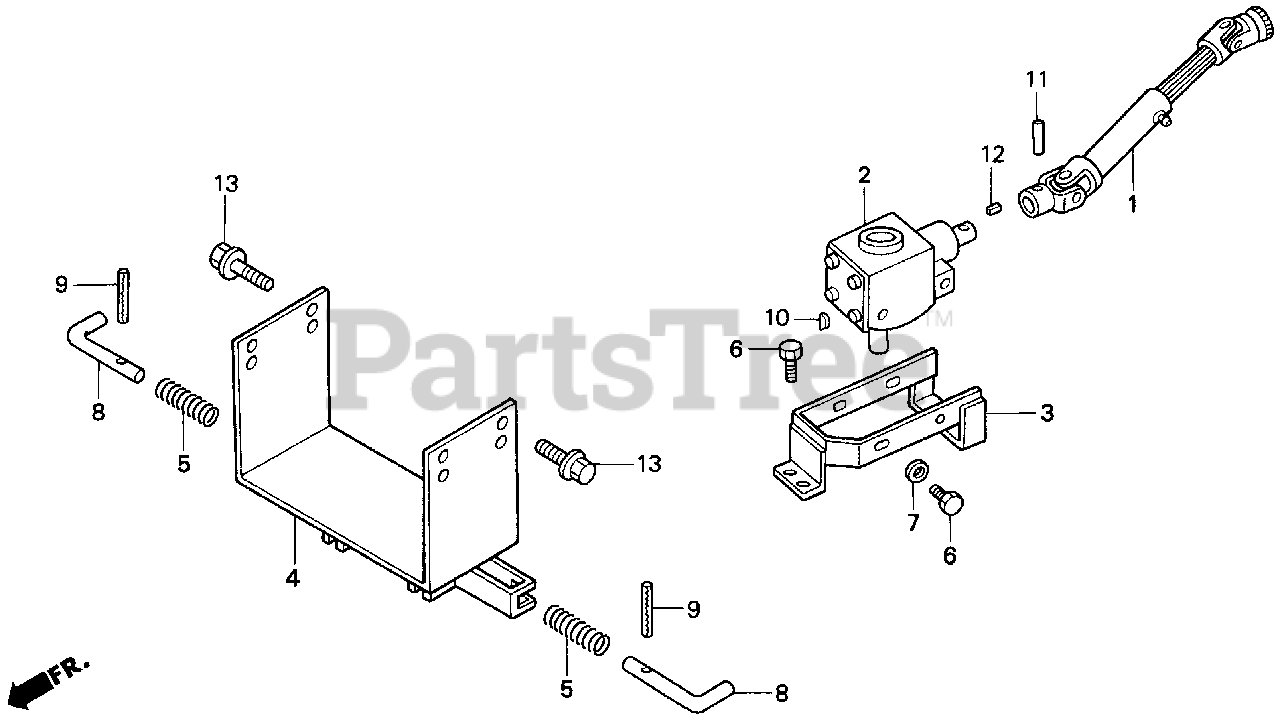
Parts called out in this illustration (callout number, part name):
1	JOINT ASSY., UNIVERSAL
2	BOX ASSY., BEVEL GEAR
3	BRACKET, GEAR CASE
4	BRACKET, FR. LINK
5	SPRING, FR. LINK
6	BOLT (3/8NCX1 HHCS)
7	WASHER (3/8 STD LOCK)
8	PIN, FR. LINK
9	PIN, SPRING
10	KEY, WOODRUFF
11	PIN, UNIVERSAL JOINT
12	KEY, UNIVERSAL JOINT
13	BOLT, FLANGE (12X30)
